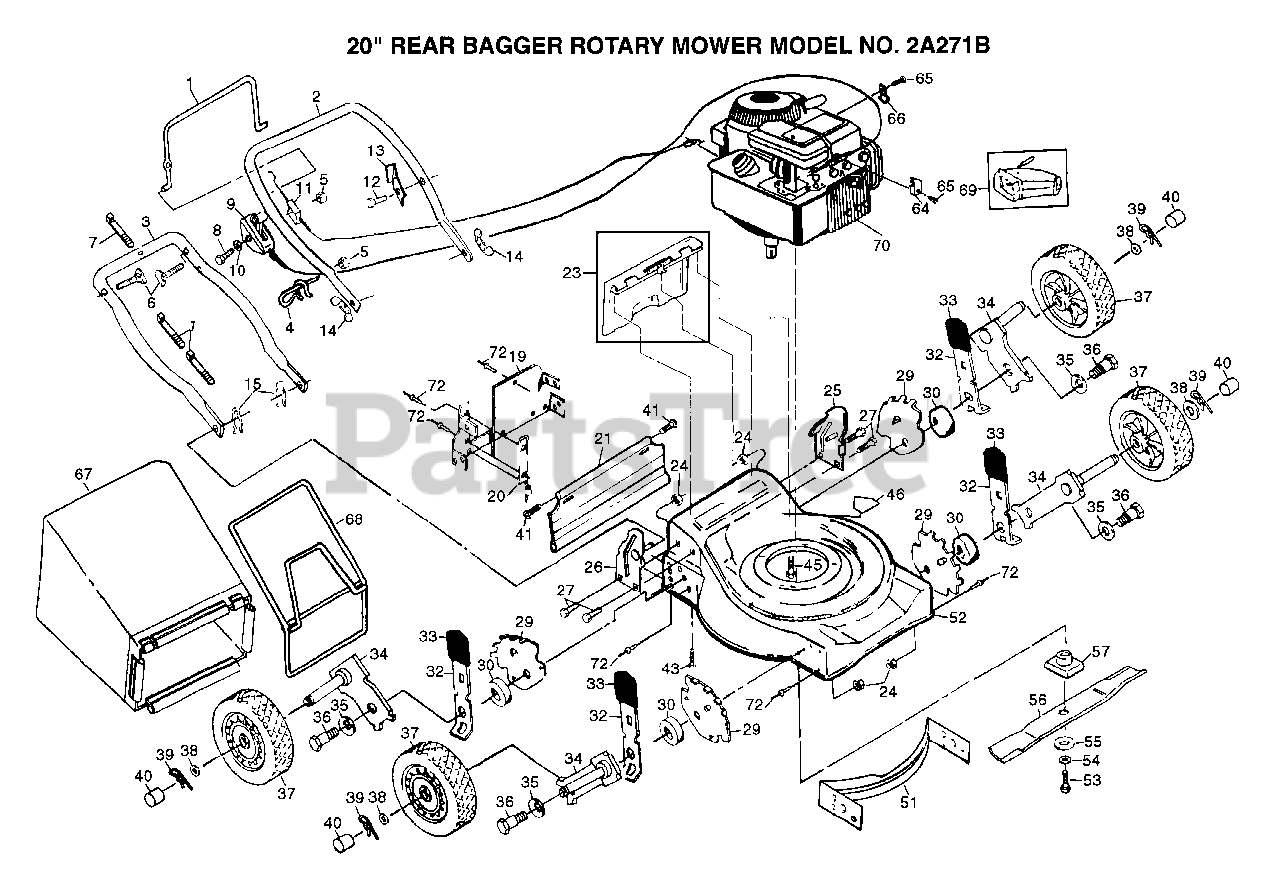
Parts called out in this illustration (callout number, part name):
1	CONTROL BAR
4	ROPE GUIDE
6	BOLT.HANDLE.LM
9	CONTROL THROTTLE
10	WASHER PM
11	"CABLE,ENG ZONE CO"
12	TAPPING SCREW
13	"BRKT,UPSTOP"
14	"NUT,WING PM"
15	HAIRPIN COTTER
19	PLATE.BACK.20RD
23	"KIT, REAR DOOR PM"
24	LOCKNUT PM
27	SCREW
29	BRACKET.WHL.ADJ.9
32	SPRING SELECTOR
33	KNOB PM
34	AXLE ARM
35	"WASHER, BELLEVIL."
37	WHEEL.ASM
38	WASHER
39	RETAINER CLIP PM
40	HUB CAP-PLASTIC
41	HINGE SCREW
43	SCREW
45	SCREW
46	DECAL HYT
52	KIT.HSG.20RD
53	SCREW
54	LOCKWASHER
55	"WASHER,HARDEN"
56	BLADE.STAND.20INC
57	BLADE ADAPTOR
65	SCREW PM
66	GUIDE CLIP PM
67	GRASS BAG
68	CATCHER FRAME
72	BLIND RIVET
